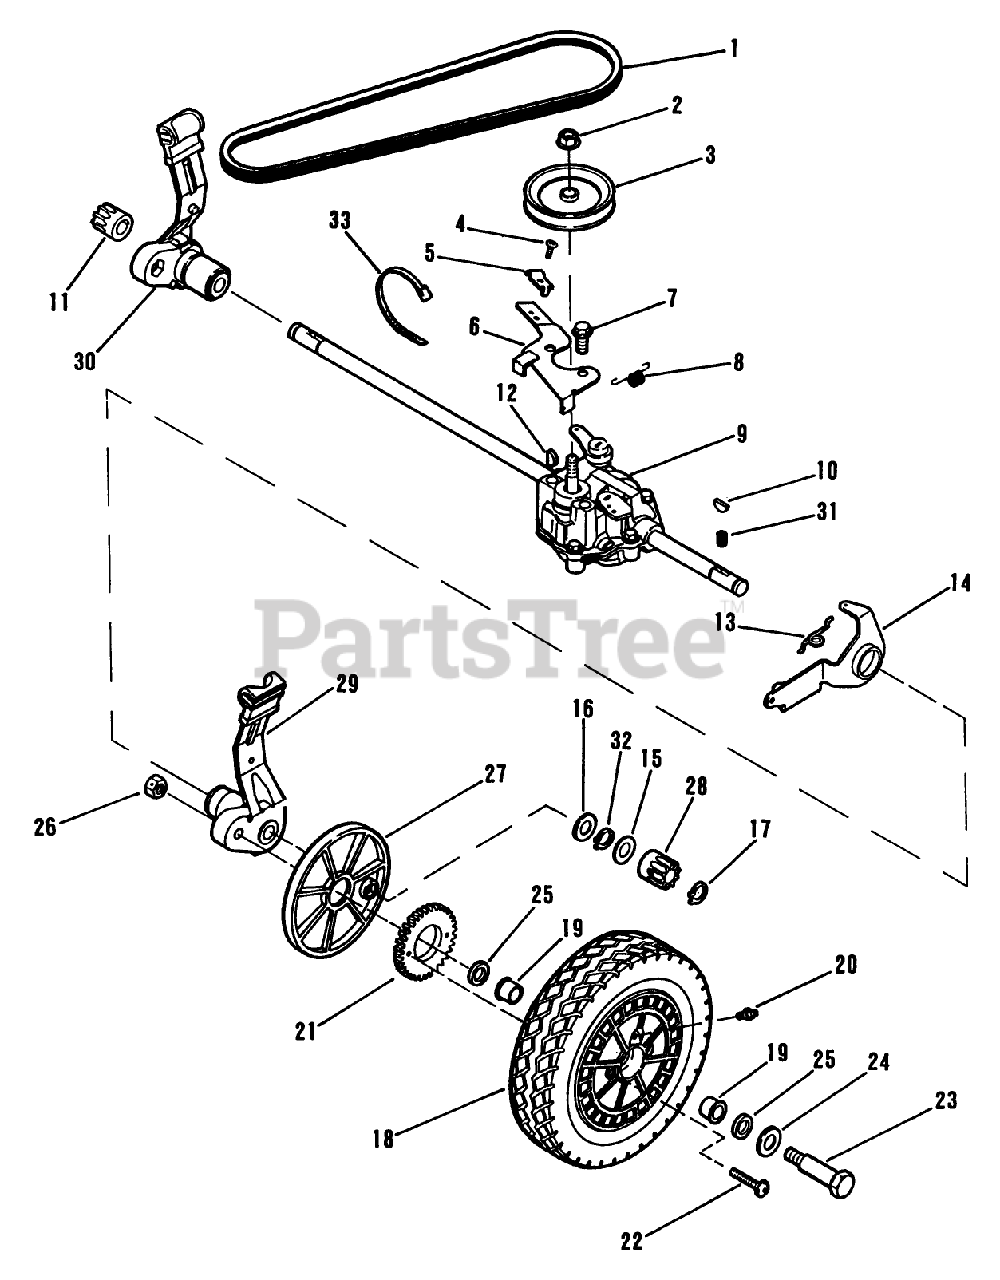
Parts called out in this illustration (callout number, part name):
1	V BELT SM
3	PULLEY TRANS ADAMS
5	CLAMP-CABLE
8	SPRING-EXTENSION
9	TRANSMISSION ASSEM
10	KEY
11	PINION(R)MET ALLEG
12	KEY GALGER
13	LINK
15	THRUST WASHER
16	WASHER-THRUST
17	RETAINING RING
19	BEARING
20	FITTING LINCOLN
22	SCREW-PH
23	BOLT WHEEL QUAL
24	SPACER
25	WASHER
26	LOCKNUT
28	PINION(L)MET ALLEG
29	HT. ADJ. ARM AY-L
30	HT. ADJ. ARM AY-R
31	SPRING
32	RET RING
